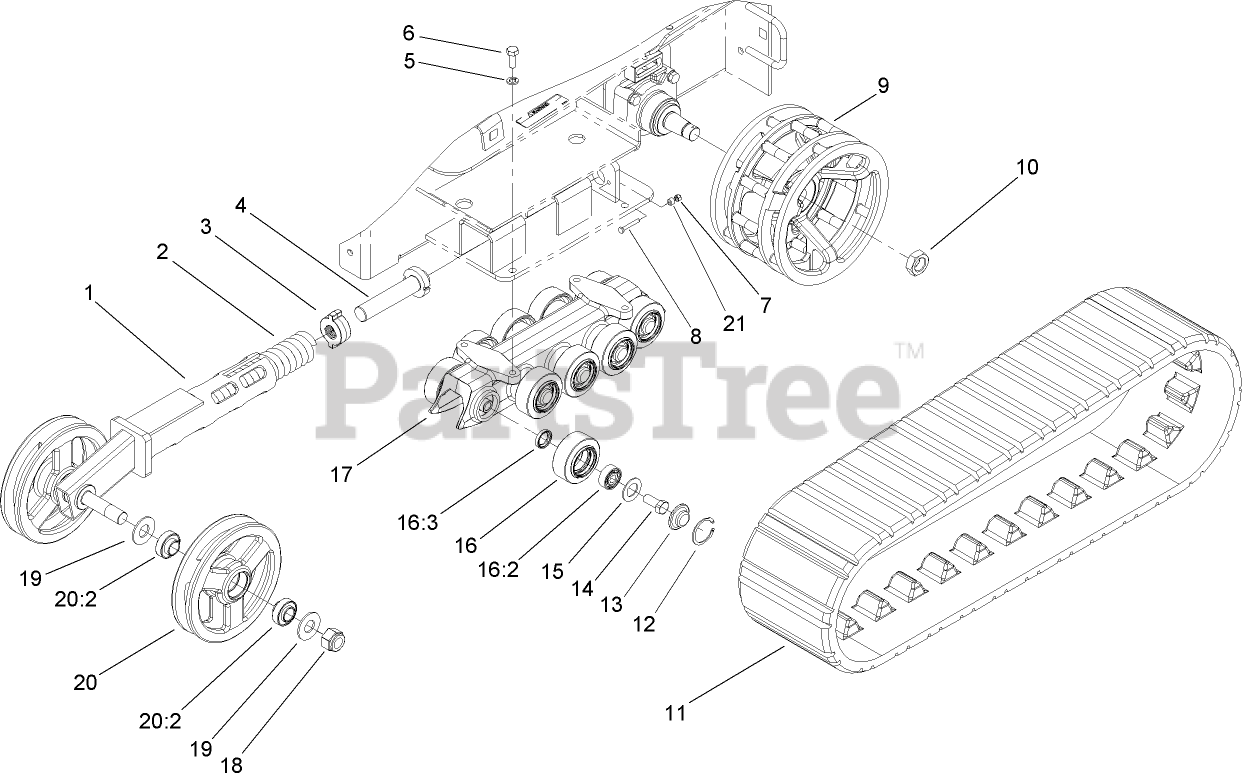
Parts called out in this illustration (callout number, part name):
1	TENSIONER ARM ASM
2	SPRING-COMPRESSION
3	BLOCK-TENSIONER
4	BOLT-TENSIONER
5	WASHER-LOCK
6	SCREW-HH
7	NUT-LOCK, NI
8	SCREW-HH
9	WHEEL-DRIVE
10	NUT-HEX
11	TRACK
12	RING-SNAP, INTERNAL
13	CAP-WHEEL, BEARING
14	SCREW-HH
15	Gasket-Bogie
16	Road Wheel ASM
16:2	BEARING
16:3	SEAL-OIL
17	GUIDE-TRACK
18	NUT-HEX, NI
19	Washer-Flat
20	Tensioner Wheel ASM
20:2	Bearing-Ball
21	SPACER
